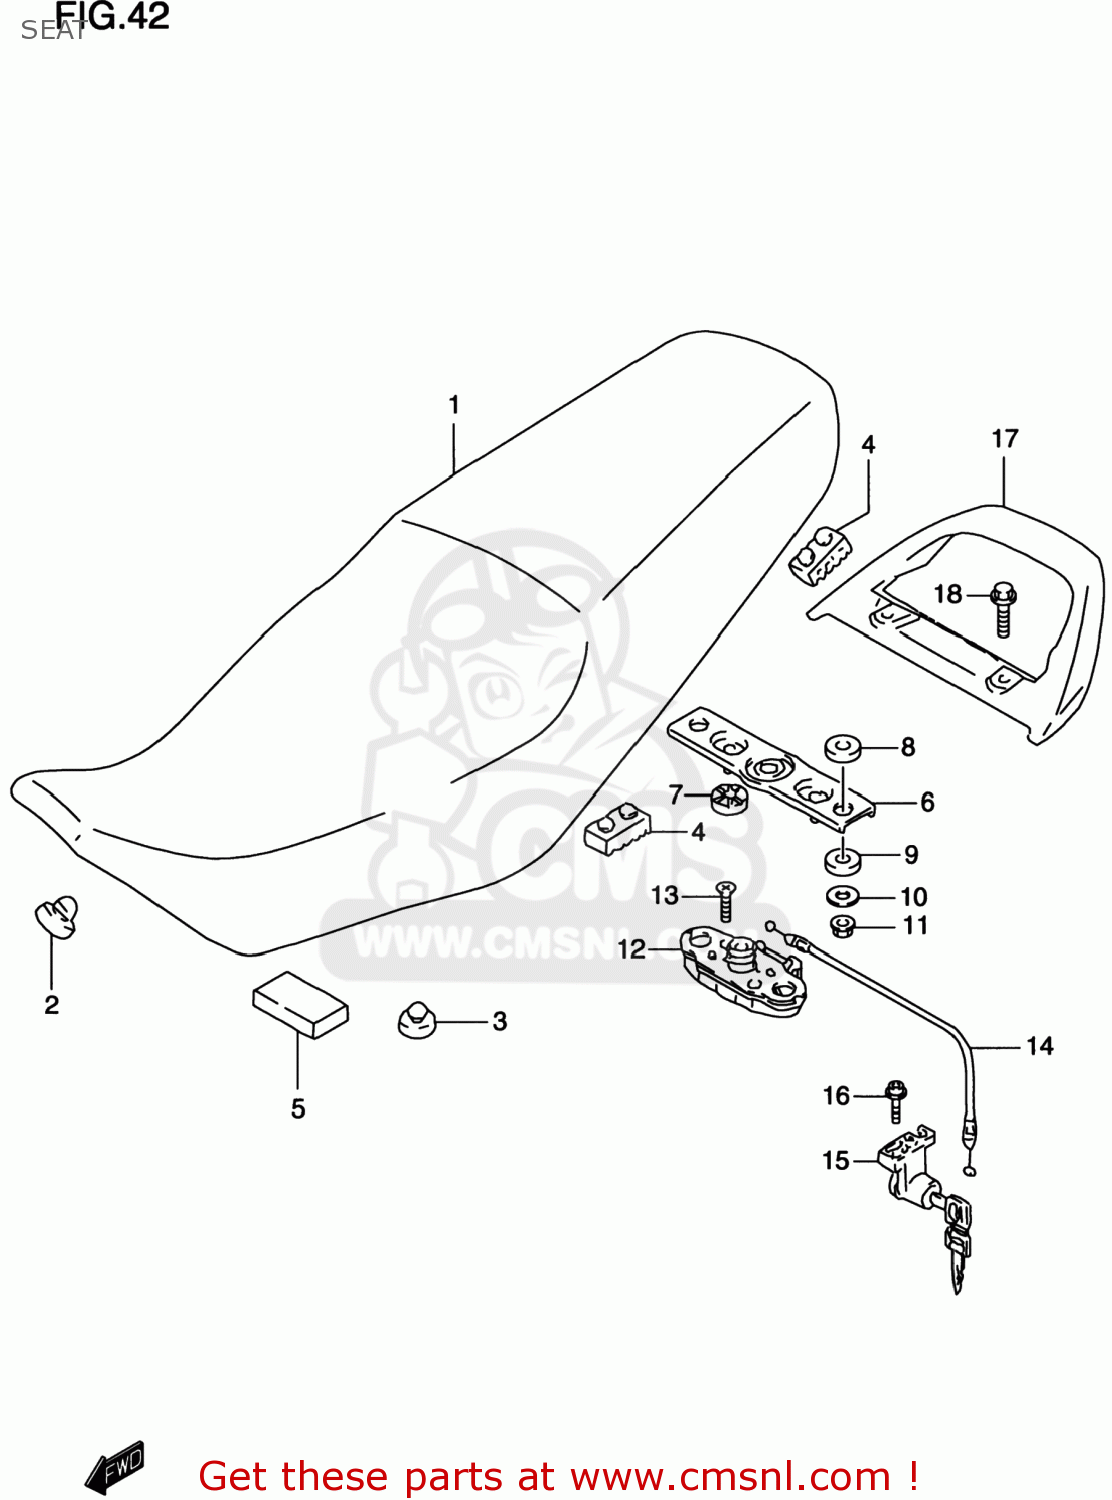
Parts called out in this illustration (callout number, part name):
1	SEAT SET
2	CUSHION
3	CUSHION
4	CUSHION,SEAT(40X20X15)
5	CUSHION(30X60X10)
6	STRIKER,SEAT LOCK
7	CUSHION,SEAT LOCK(10X22X6)
8	CUSHION,UPR
9	CUSHION,LWR
10	WASHER
11	NUT
12	LOCK ASSY,SEAT STRIKER
13	SCREW
14	CABLE,SEAT LOCK
15	LOCK SET,SEAT
16	SCREW
17	HANDLE,PILLION RIDER
18	BOLT
